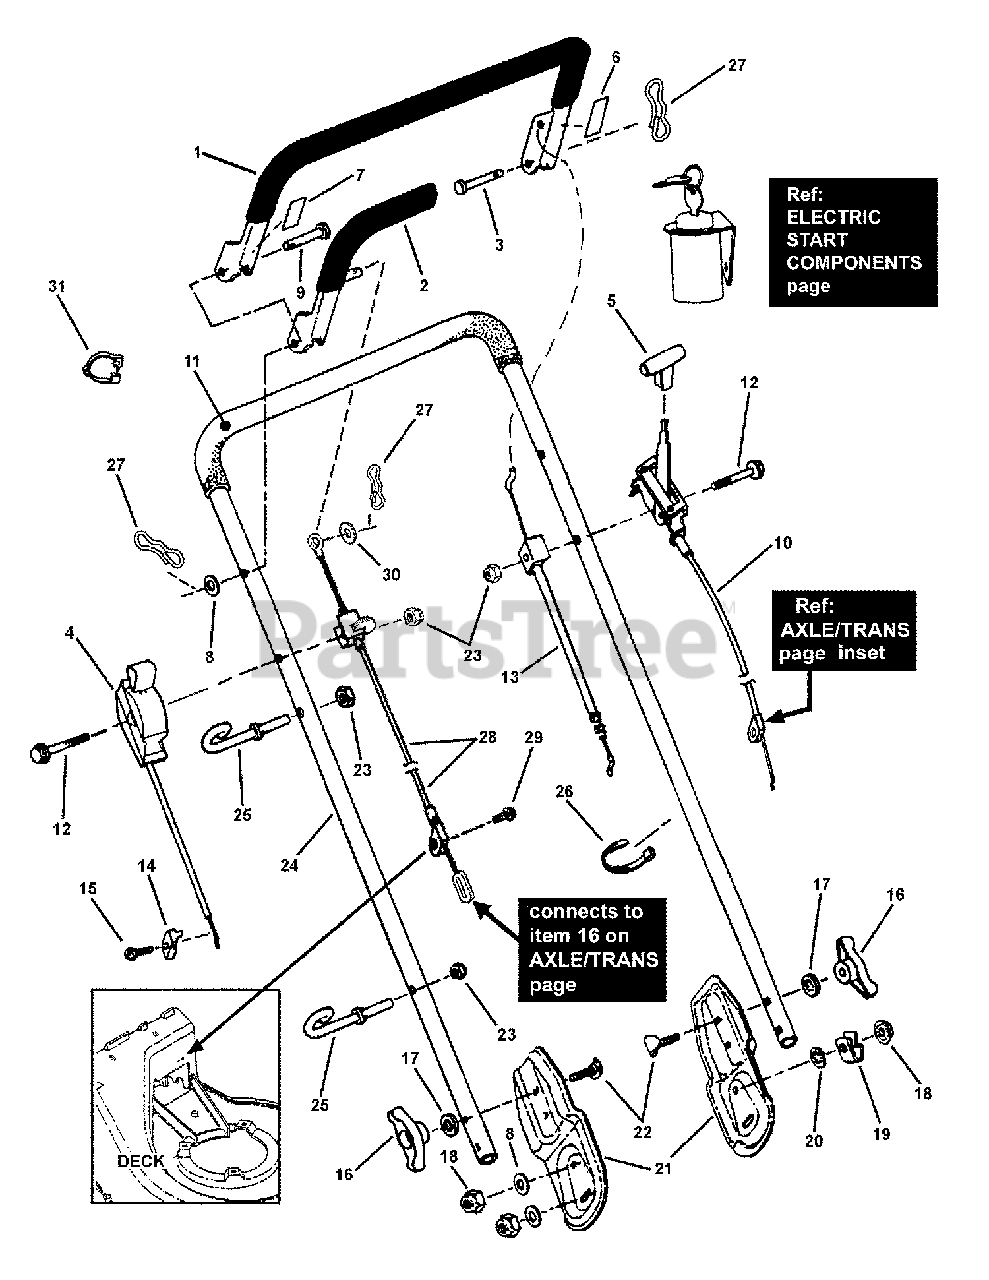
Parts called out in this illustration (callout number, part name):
1	CONTROL, Blade (ELP21502KWV)
1	CONTROL, Blade (ELP21602 & ELP21602E)
2	WELDMENT, Ground Speed Control (Coated)
3	PIN, 5/16 x 1-7/16" Clevis
4	CONTROL, Engine Speed (+49.8/1.41")
4	CONTROL, Engine Speed (+49/2")
5	KNOB, Engine Speed & Ground Speed Control
6	DECAL, (OPC) Operator Presence Control
7	DECAL, Ground Drive, (Cast Al Comm)
8	WASHER, 5/16" Flat
9	PIN, 5/16 x 1-3/4" Clevis
10	CONTROL, Ground Speed (+56/1.85")
11	GRIP, Foam (7/8" I.D. x 21-1/2" long)
11	GRIP, Foam (1" x 21-1/2" long)
12	SCREW, 1/4-20 x 2-1/2" Hex Head Cap, GR 5
13	*CABLE ASSEMBLY, Blade Control (48.88" long)
13	*CABLE ASSEMBLY, Blade Control (51.97" long)
14	CLAMP, Engine Speed (3-Speed Control)
15	SCREW, #10-32 x 5/8" Slotted Hex Head, Self-Tap
16	KNOB, 5/16-18 Thread
17	WASHER, 5/16" Internal Tooth Lock
18	NUT, 5/16-18 Hex Nyloc
19	CLAMP, Double Tube
20	RETAINER, 5/16" Bolt (Black)
21	BRACKET, Handle (Black)
21	BRACKET, Handle (Yellow Chromate)
22	SCREW, 5/16-18 x 2" Square Neck Curved Head
23	NUT, 1/4-20 Hex Nyloc
24	HANDLE, Upper (ELP21502KWV)
24	HANDLE, Upper (ELP21602 & ELP21602E)
25	GUIDE, Rope (1/4-20 thread)
26	TIE, Wire 1.29" long (Black)
27	PIN, Bow-Tie Locking Cotter
28	CABLE, Traction Adjustable (51.20/6.38")
29	SCREW, #10-24 x 5/8" Hex Washer Self-Tap
30	WASHER, 3/16" Flat
31	CLAMP, 7/8" Double Cable
